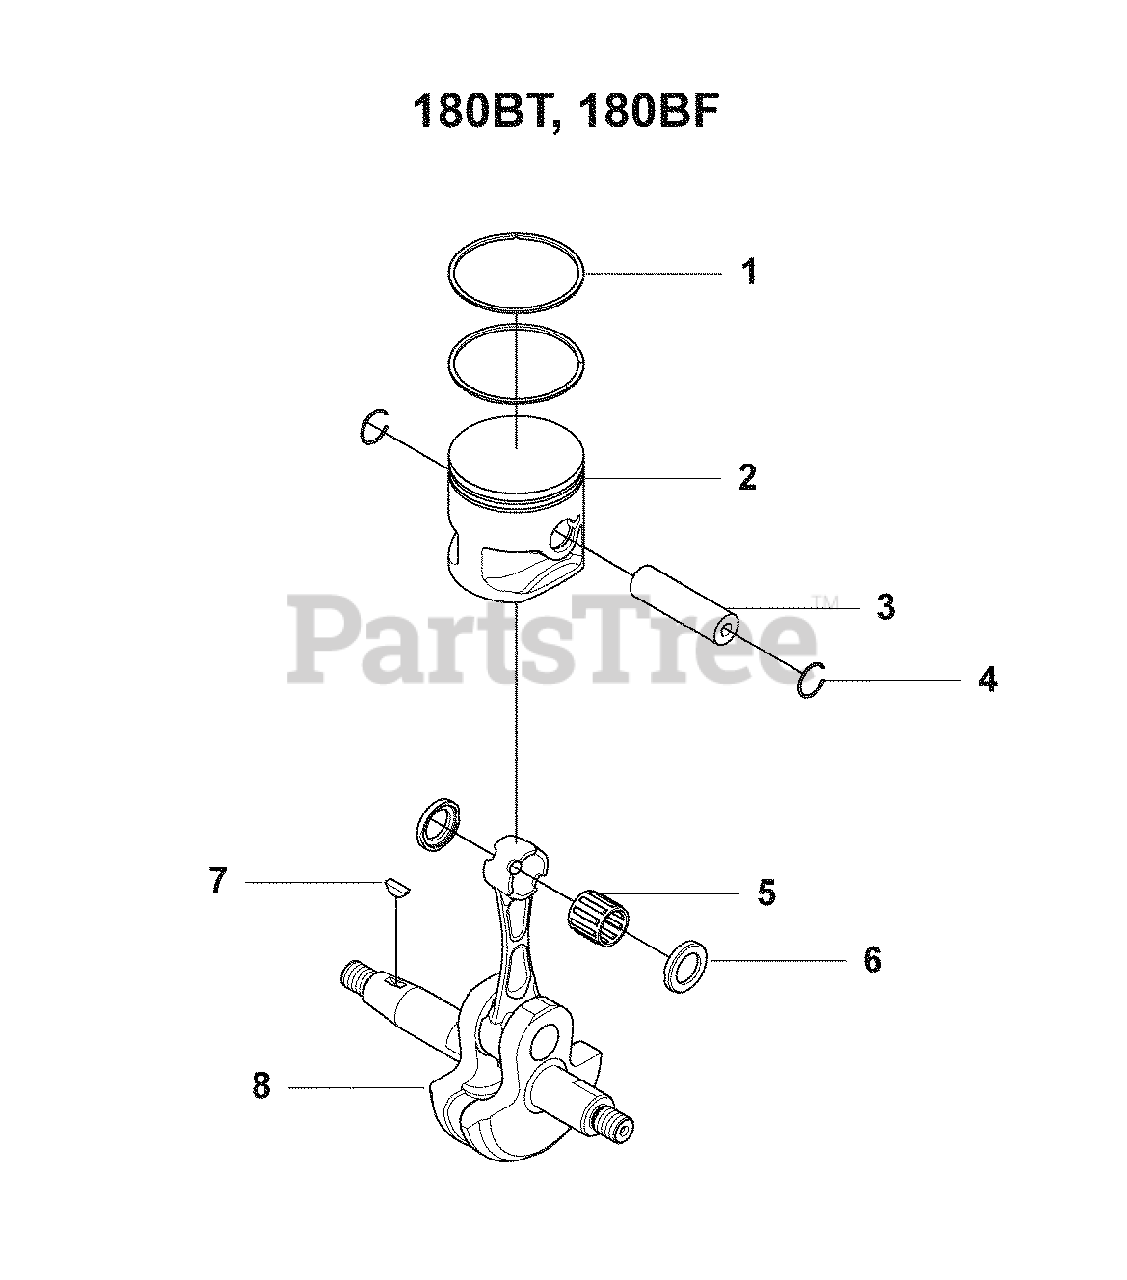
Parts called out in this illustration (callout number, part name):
1	Piston Ring, 1-Per Box
3	Piston Pin
4	Snap Ring
5	Bearing
6	Washer
7	Flywheel Key
8	Shaft, Comp
